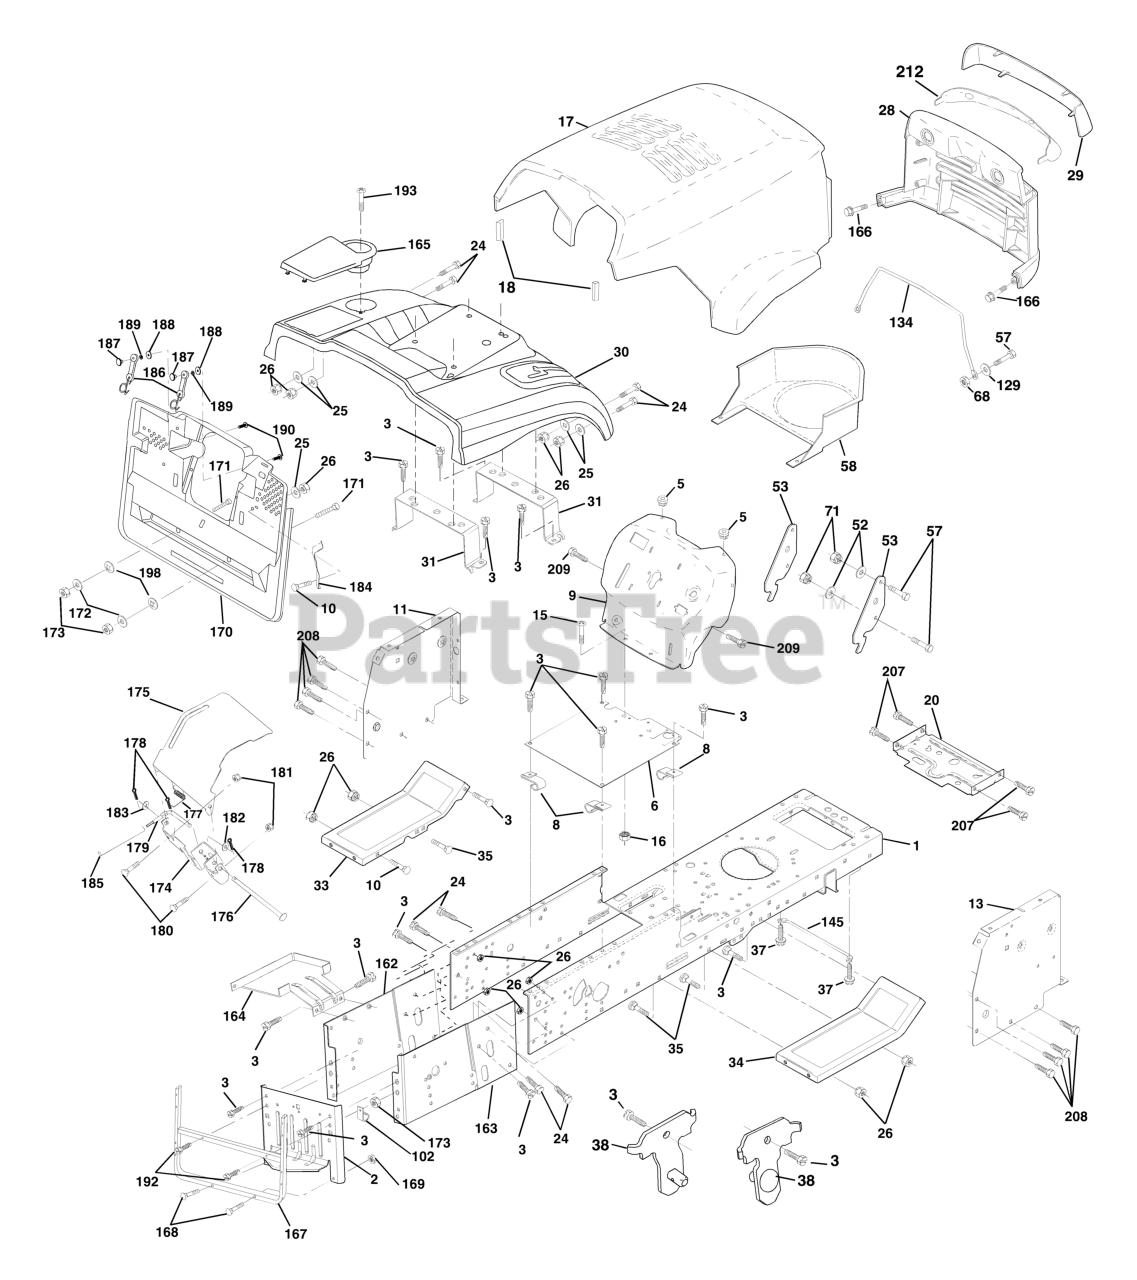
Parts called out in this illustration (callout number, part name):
1	CHASSIS STAMPING
3	SCREW 3/8-16X3/4
5	BUMPER.RUBBER.HOOD
6	SADDLE FLAT
8	CLIP,INSULATOR
10	BOLT D
11	PANEL DASH LH
13	PANEL DASH
14	SCREW LT
15	Screw, Machine, Truss Head 5/16-18 UNC x 3/4
16	NUT
17	HOOD
18	BUMPER HOOD T
20	PLATE MTG
24	BOLT
25	WASHER
26	NUT
28	GRILL
29	LENS
31	BRACKET SUPPORT FENDER
33	FOOT REST LH
34	FOOTREST RH
35	BOLT
37	Screw Thdrol 5/16-18 x 1/2 TYT
38	BRACKET
52	WASHER
53	BRACKET PNT PICK OFF LT/PL
57	BOLT
58	AIR DUCT P/L/LT
68	NUT
71	NUT.CROWNLOCK.1/4
102	CLIP T
129	WASHER
134	ROD SUPPORT HOOD LT/PL HUS.
145	ROD PIVOT CHASSIS/HOOD
165	COVER BATTERY
166	SCREW
167	SUPPORT.ASM.BACKPLATE
168	BOLT.ROUND.HEAD.SQUARE.NECK
169	NUT T
170	COVER BACKPLATE
171	BOLT
172	WASHER
176	HINGE PIN
177	SPRING COVER LH
178	COTTER PIN
180	BOLT RB
181	LOCKNUT
183	WASHER
185	TUBE LEVER
186	LATCH ASSY
187	WELDNUT
189	LOCKWASHER #10
190	SCREW
192	SCREW LT
193	Screw Truss 1/4-20 x 3/4
194	SCREW 3/8-16X3/4
207	SCREW, 5/16-18 X 1/2
208	SCREW 3/8-16X1/2
209	SCREW, 3/8-16X3/4
212	INSERT LENS REFLECTOR
